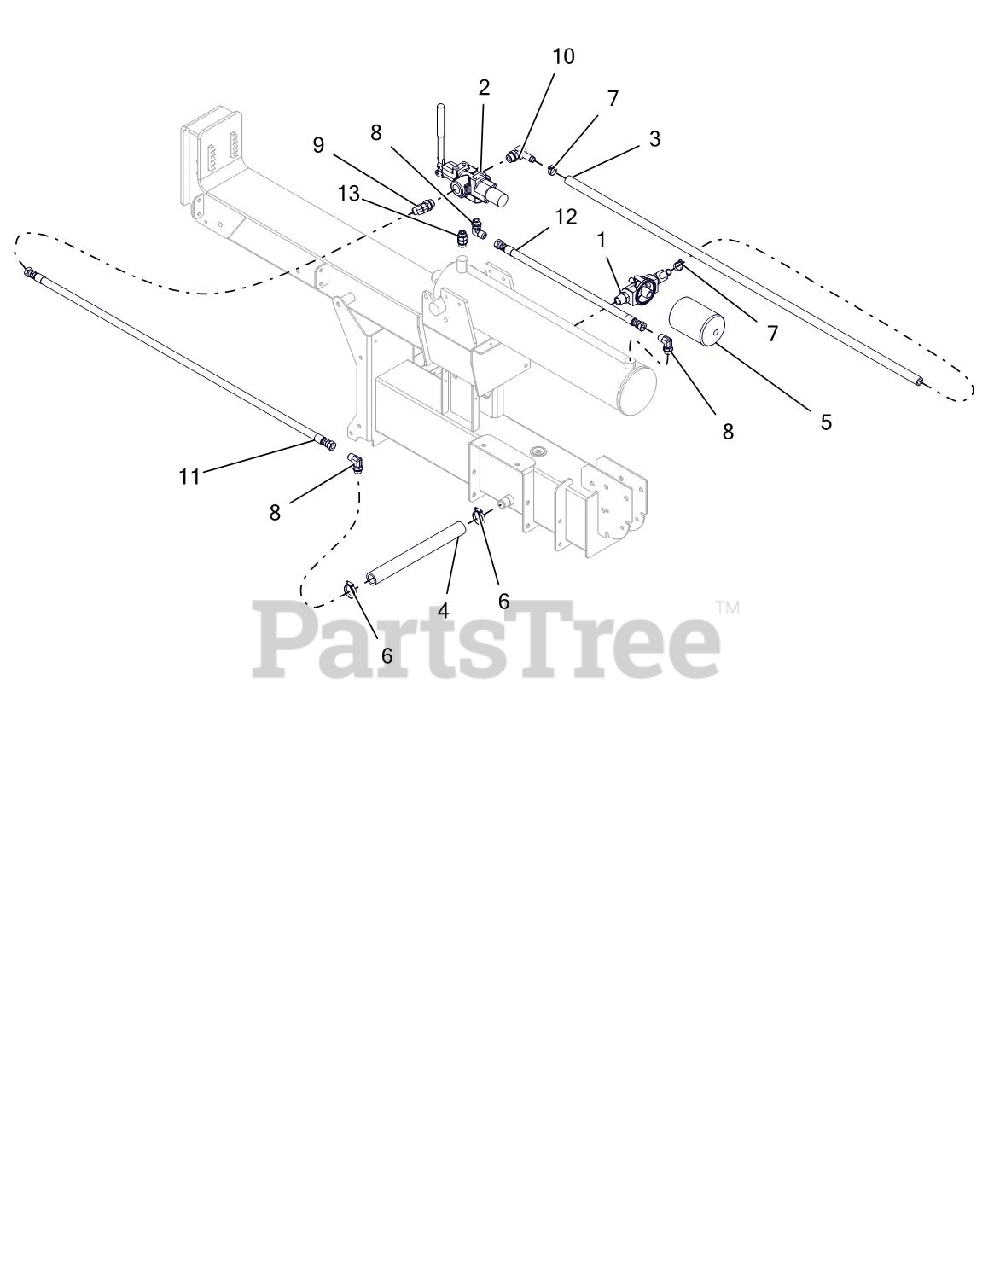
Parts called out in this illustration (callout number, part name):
1	ASM, FILTER HEAD
2	VALVE CONTROL-SPLITTER
3	HOSE,HYD RETURN 10LOLA X 53"
4	HOSE,HYD SUCTION 16G4H X 13.5
5	FILTER,HYDRAULIC OIL-NO BYPASS
6	CLAMP-HOSE 1.50X.81X1.42
7	CLAMP,.88 DIA. HOSE
8	FTG,HYD 6801-8-8
9	FTG,HYD 6802-8-10
10	FTG,HYD 4601-10-10
11	HOSE, ASM - 46"
12	HOSE, HYD - 22"
13	FTG, HYD - STR 08MAORB-08MORB
